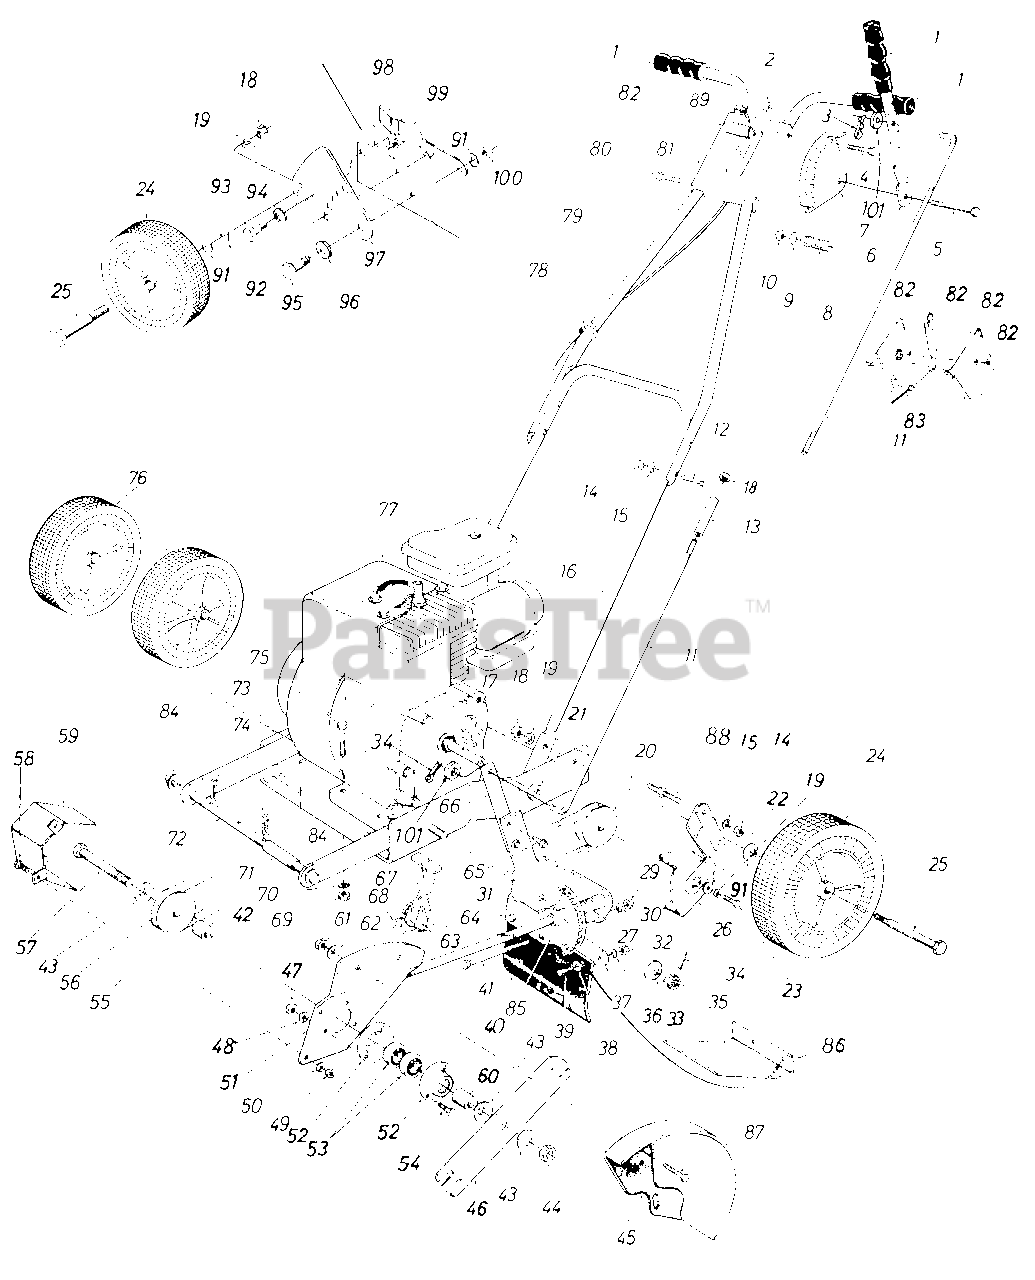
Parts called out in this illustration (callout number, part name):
1	Black Grip
2	Hex L.-Nut 1/4-20 Thd.
3	Cotter Pin 1/8" Dia.
4	Hex Bolt 1/4-20 x 1.25" Lg.*
5	Hex Bolt 5/16-18 x 1.75" Lg.*
8	Compression Spring 1.38" Lg.
9	Fl.-Wash. .344" I.D.
10	Hex L.-Nut 5/16-18 Thd.
11	Clutch Rod Half 18.25" Lg.
12	Carriage Bolt 1/4-20 x 1.25" Lg.*
13	Rod Adjustment Link
14	Hex Nut 1 4 20 Thd.*
15	L.-Wash. 1/4" I.D.*
16	Lower Handle (Painted)
17	Sq. Key 3/16" x .75" Lg.
18	Hex Nut 3/8-16 Thd.*
19	L.-Wash. 3/8" I.D.f
20	Engine Pulley
21	Spacer.75" I.D.
22	Fl.-Wash. .385" I.D.
23	Hex Bolt 3/8-24 x 1" Lg.
24	Rear Wheel Ass'y. 8" x 1.75"
25	Shoulder Bolt .498" Dia.
26	Belt Guard Ass'y.
27	Compression Spring
29	Hex Nut 5/16-18 Thd.*
30	L.-Wash. 5/16" I.D.*
31	Spring Pin Spir. 3/16" Dia.
32	Hex Nut 1/4-20 Thd.*
33	Bell.-Wash. .535" I.D.
34	Cotter Pin 1/8" Dia.*
35	Hex Slotted Nut 1/2-20 Thd.
36	L.-Wash. 1/4" I.D.*
39	Hex Bolt 1/4-20 x .50" Lg.*
41	Hex Bolt 5/16-18 x 4.5" Lg.*
42	Spacer 1.030" 4.
43	Bell.-Wash. .63" I.D.
44	Hex Ins. L.-Nut 5/8-18 Thd.
47	Hex Nut 1/4-20 Thd.*
48	L.-Wash. 1/4" I.D.*
49	Hex Nut 1/4-20 Thd.*
50	L.-Wash. 1/4" I.D.*
53	Ball Bearing .62" I.D.
54	Hex Bolt 1/4-20 x .62" Lg.*
55	3/8" "V" Pulley
56	"V" Belt
57	Hex Bolt 5/8-18 x 4.5" Lg.*
58	Hex Bolt 1/4-20 x .625" Lg.*
60	Sleeve.90" Lg.
61	Hex Nut 5/16-18 Thd.*
62	Bell.-Wash. .345" I.D.
63	Spring Pin Spir. 1/4" Dia.
68	Torsion Spring
69	Hex Nut 5/16-18 Thd.*
70	L.-Wash. 5/16" I.D.*
71	Spacer 1.62" Lg.
72	Axle 8.75" Lg. Front)
73	Base Ass'y.
74	Hair Pin Cotter 1/2" Dia.
75	Hex Bolt 5/16-18 x 1.5" 4.*
76	Front Wheel Ass'y. 7" x 1.50"
77	Engine
78	Cable Tie
79	Upper Handle (Painted)
80	Hex Bolt 1/4-20 x 1" Lg.
83	Throttle Control Wire 30" 4.
84	Push Cap 1/2"Dia.
85	Spacer 3.765" 4.
88	Stud 1/4-20 x 2.12" 4.
89	Self-Tap Scr. #l0 x .50" 4.
91	Bell.-Wash. .40" I.D.
92	Fl.-Wash. .39" I.D.
93	Shld. Bolt.5" Dia.
94	Bell-Wash. .515" I.D.
95	Shld. Bolt .50" Dia.
96	Fl.-Wash. 51" I.D. x 1"
99	Spring Adj. Lever
100	Hex Jam Nut 3/8-16 Thd.
101	Fl-Wash 3/8" I.D.
